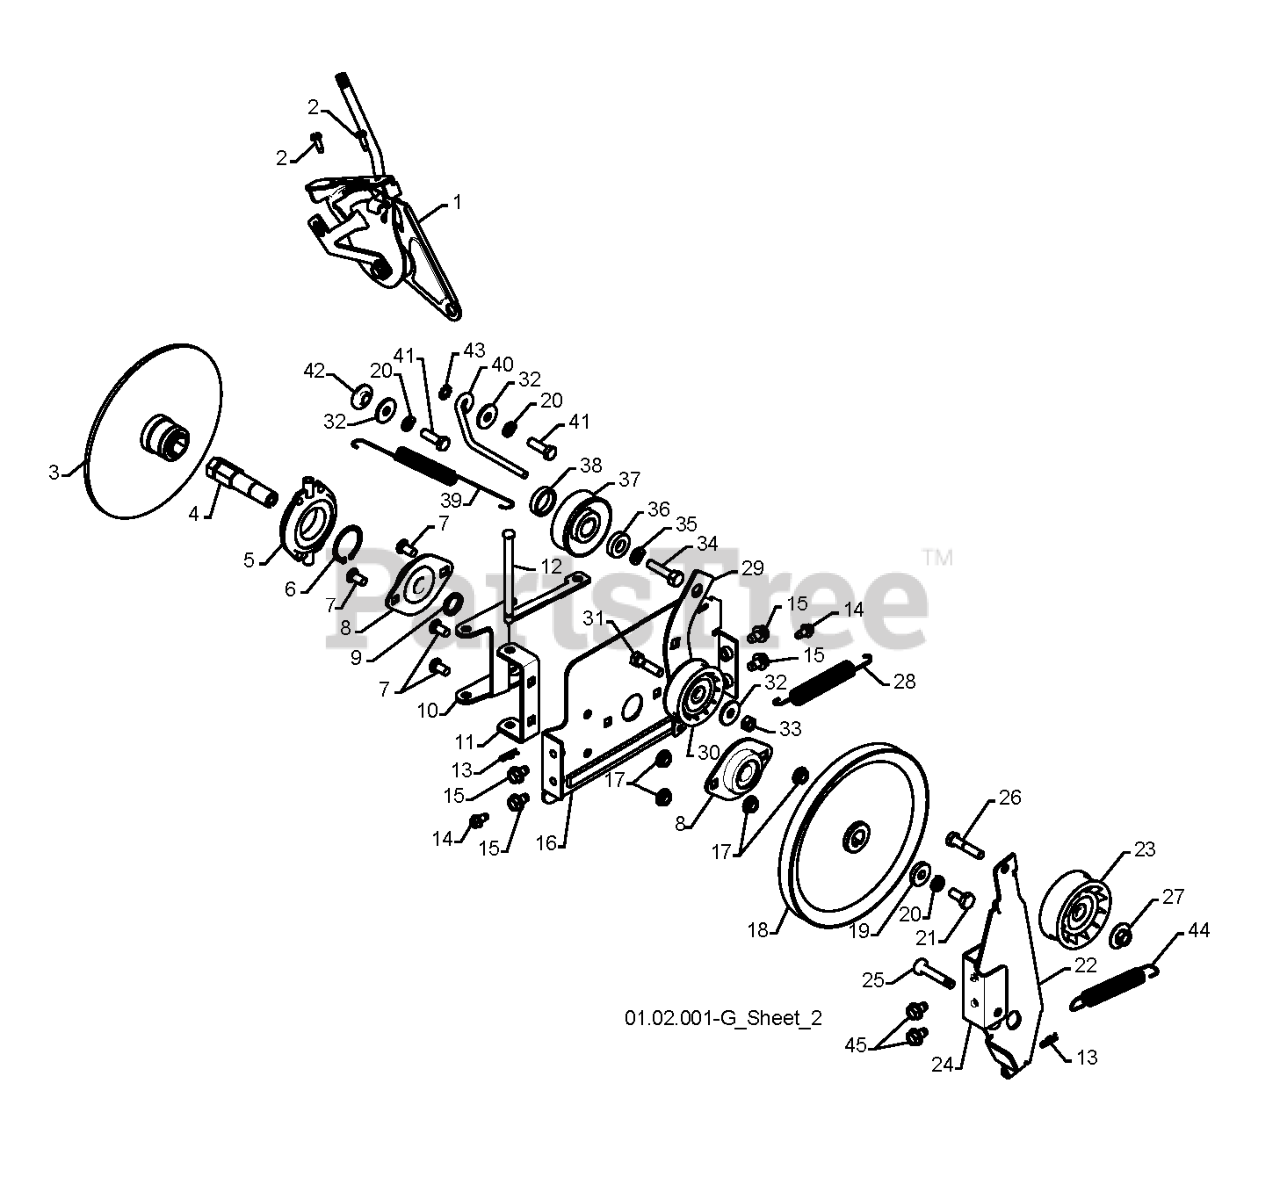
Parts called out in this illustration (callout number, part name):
1	HEAD ASSY SPEED
2	SCREW #10-24 X 5/8
3	DRIVE PLATE WELDMENT
4	SHAFT.HEX.SHORT
5	TRUNNION BEARING ASSY
6	RETAINING RING (2 2)(3 2)
7	BOLT
8	BEARING FLANGE
9	SPACER, BEARING
10	LEVER.SHIFTER.PLATE.BLACK
11	BRACKET, SHIFTER SUPPORT
12	PIN, PIVOT LEVER
13	RETAINER CLIP PM
14	SCREW
15	Screw 5/16-18 x 1/2 Hex, Self Tapping 5/16-18 x 1/2
16	PLATE.DRIVE.MOUNTING.BLACK
17	NUT.FLANGE.5/16
18	PULLEY.TRACTION.7.75
19	WASHER, FLAT
20	WASHER.LOCK.HVY.HLCL.SPR.5/16
21	Screw, Hex Head 5/16-18 x 3/4
22	ARM.IDLER.BRAKE.BLACK
23	PULLEY.W/SPACER.2.75
24	BRACKET, IDLER PIVOT
25	PIN, IDLER PIVOT
26	HEX BOLT
27	LOCKNUT 5/16-18
28	RP SPRING, TRACTION IDLER
29	ARM, IDLER
30	PULLEY.W/SPACER.2.25
31	BOLT.5/16-18X1-1/4 FULL.THREAD
32	STEEL WASHER
33	NUT.CENTERLOCK.5/16-
34	SCREW, HEX HD 3/8-24 X 1-3/8
35	LOCKWASHER
36	WASHER, FLAT 3/8
37	PULLEY,ENGINE TRACTION DRIVE
38	SPACER.ENGINE.PULLEY
39	SPRING.RETURN
40	BELT.GUIDE.RH
42	RP BUSHING, IDLER PIVOT
43	WASHER EXT TOOTH LOCK 5/16
44	SPRING, BRAKE
45	SELF-TAPPING SCREW 5/16-18X3/4
